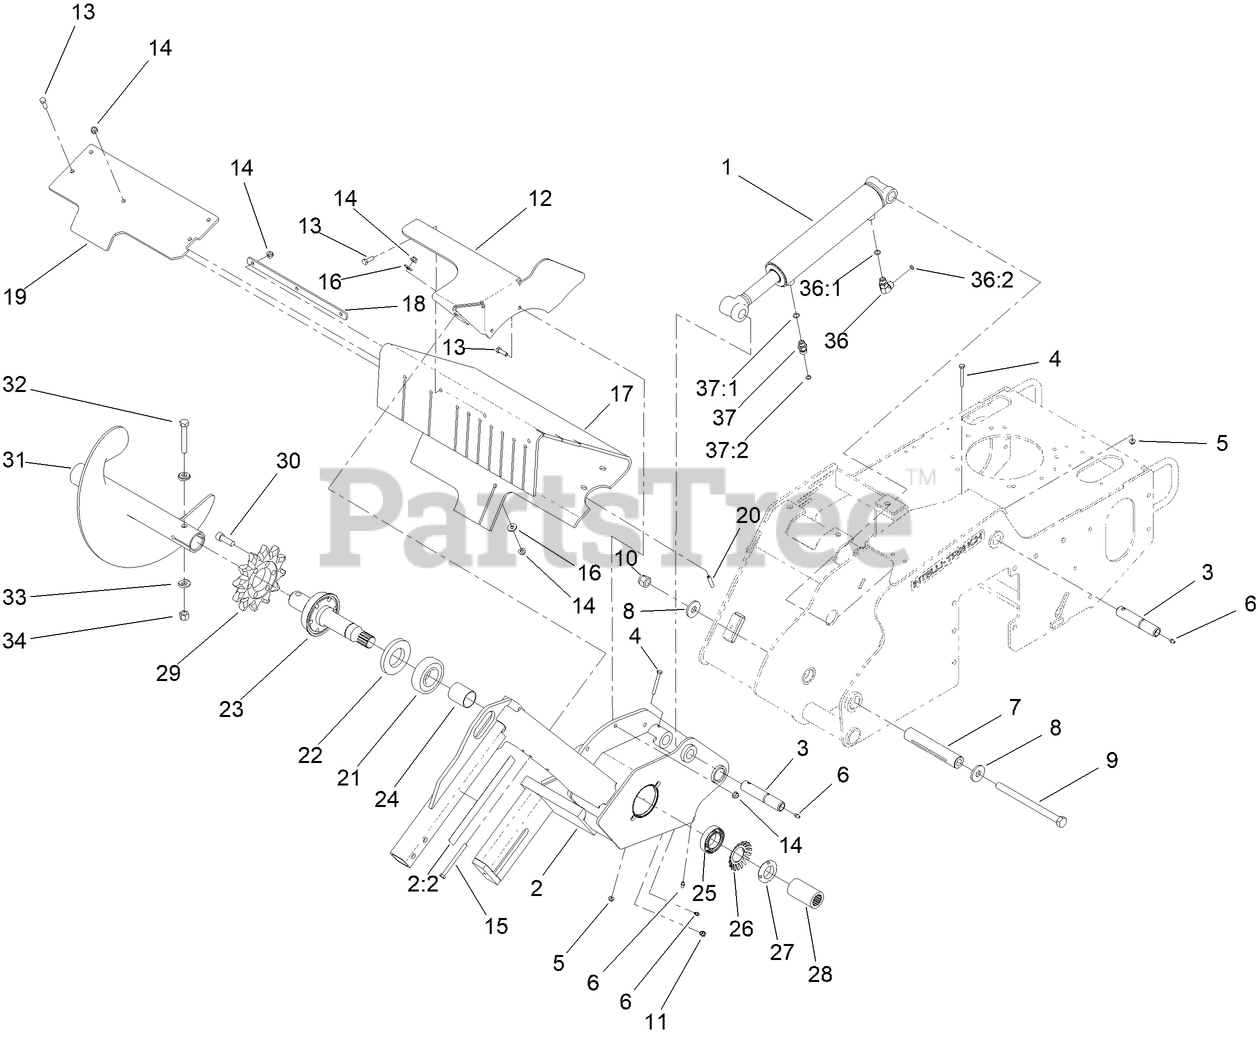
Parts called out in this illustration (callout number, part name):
1	HYDRAULIC CYLINDER ASM
2	TRENCHER HEAD ASM
2:2	DECAL-DANGER
3	PIN-PIVOT
4	SCREW-HH
5	NUT-HF
6	FITTING-GREASE
7	SPACER-PIVOT
8	WASHER-HARDENED
9	BOLT-HH
10	NUT-LOCK, NI
11	FITTING-LUBE
12	BRACKET-SHIELD
13	SCREW-HH
14	NUT-HF, NI
15	SCREW-HH
16	WASHER-FLAT
17	SHIELD-DIRT
18	PLATE-STRAP, SHIELD
19	BAR-CLAMP
20	SCREW-HSH
21	BEARING-BALL
22	SEAL-GREASE
23	SHAFT-TRENCHER
24	SPACER
25	BEARING-BALL
26	LOCKWASHER-BEARING
27	LOCKNUT-BEARING
28	COLLAR-SPLINED
29	SPROCKET-TRENCHER
30	SCREW-HSH
31	AUGER-TRENCHER
32	SCREW-HH
33	WASHER-SADDLE
34	NUT-LOCK, NI
36	FITTING-ELBOW, 90 DEG
36:1	O-RING
36:2	O-RING
37	VALVE-CHECK
37:1	O-RING
37:2	O-RING
